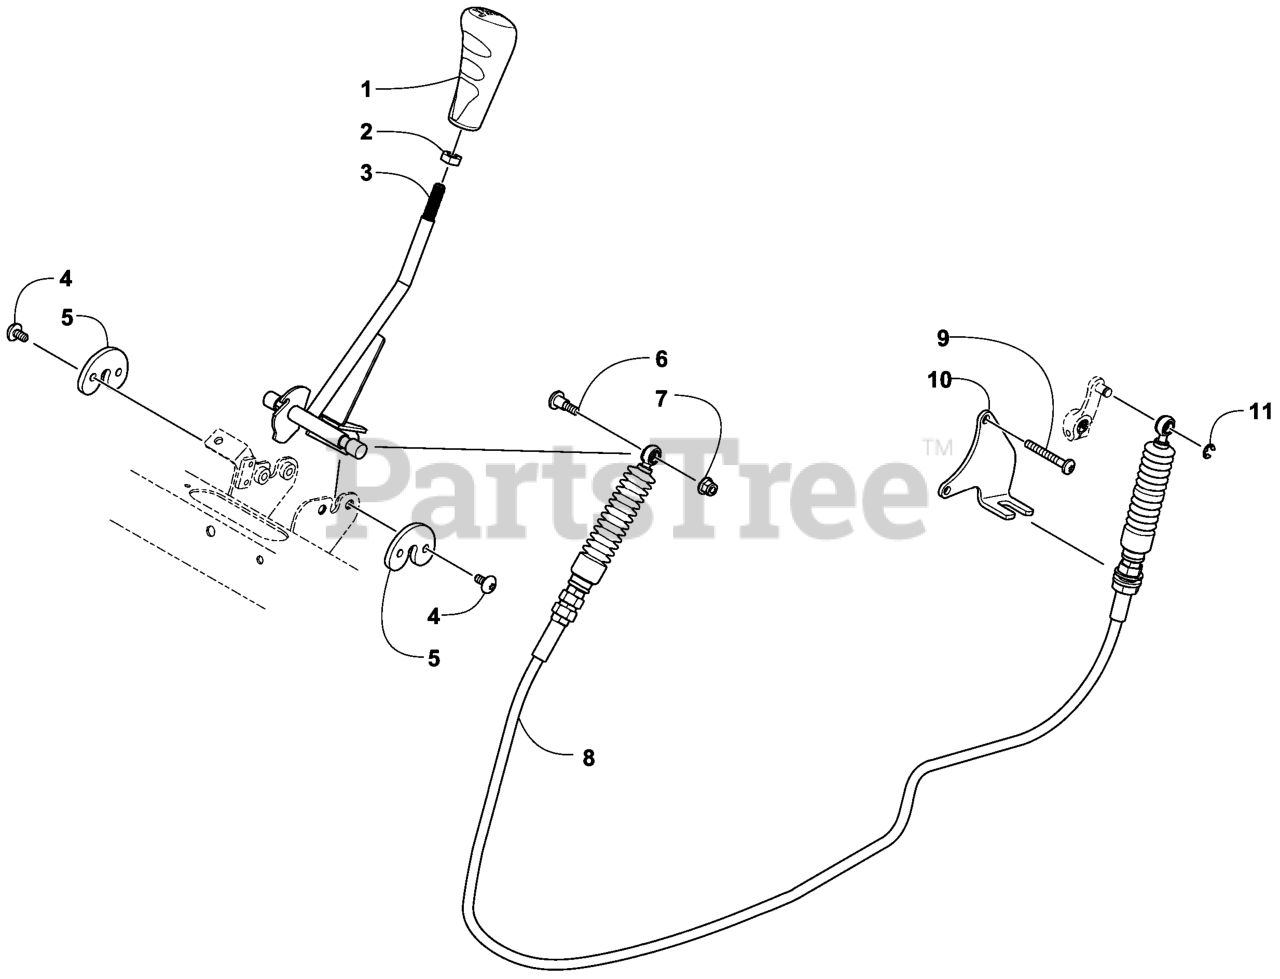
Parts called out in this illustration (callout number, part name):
1	KNOB-SHIFT
2	NUT-JAM
3	AXLE-SHIFT(DASH)
4	SCREW-TSPH
5	RETAINER-SHIFT LINKAGE
6	SCREW-SHOULDER
7	LINKAGE,LOWER CALIPER RH
10	BRACKET-SHIFT CABLE ENGIN
